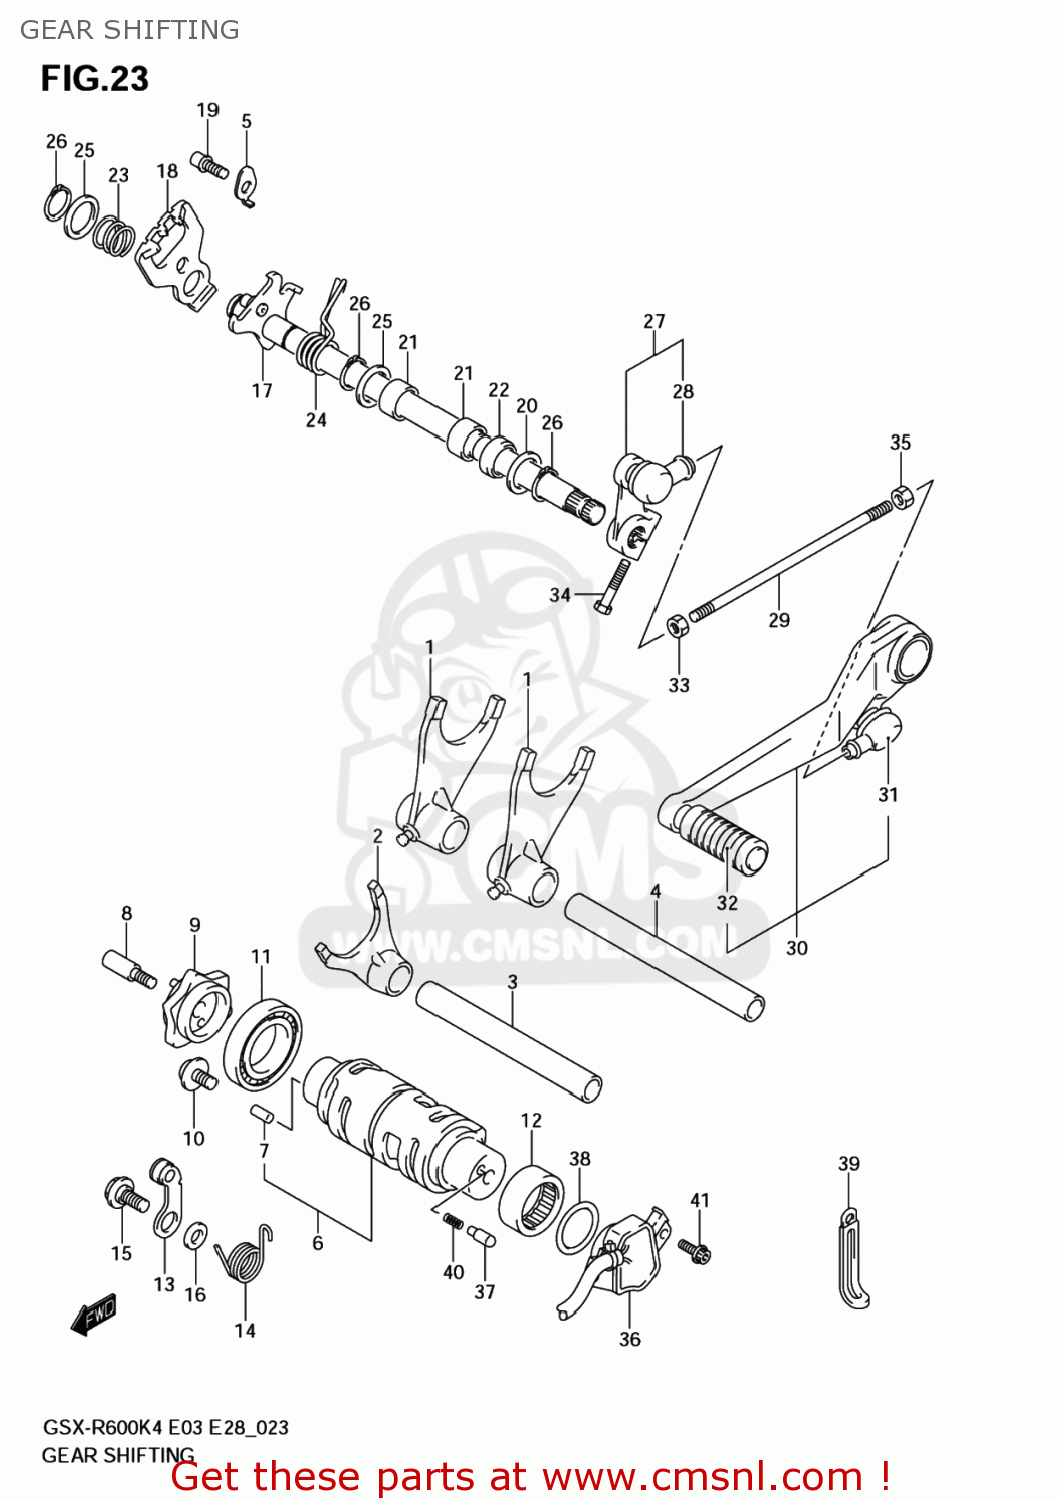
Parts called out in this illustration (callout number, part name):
1	FORK,GEAR SHIF
2	FORK,GEAR SHIF
3	SHAFT,GEAR SHIFT FORK
4	SHAFT,GEAR SHIFT FORK NO.1
5	RETAINER,GEAR SHIFT FORK SHAFT
6	CAM,GEAR SHIFT
7	PIN
8	BOLT,GEAR SHIF
9	PLATE,GEAR SHIFT CAM
10	SCREW(6X12)
11	BEARING(25X47X8)
12	BEARING(25X32X12)
13	STOPPER,SHIFT CAM
14	SPRING,SHIFT CAM STOPPER
15	BOLT(6X14.3)
16	WASHER
17	SHAFT,GEAR SHIFT
18	PLATE,GEAR SHIFT CAM DRIVE
19	STOPPER,GEAR SHIFT ARM
20	WASHER(14X29X0.8)
21	BEARING(14X20X12)
22	SEAL,OIL(14X22X6)
23	SPRING
24	SPRING
25	SHIM(14X22X1)
26	CIRCLIP
27	ARM,GEAR SHIFT LINK
28	COVER,DUST
29	ROD,GEAR SHIFT LINK
30	LEVER ASSY,GEAR SHIFT
31	COVER,DUST
32	RUBBER,GEAR SHIFT PEDAL
33	NUT
34	BOLT
35	NUT
36	BASE ASSY,GEAR SHIFT TERMINAL
37	PIN(5X15.5)
38	O RING(D:2.4,ID:25.7)
39	CLAMP(L:45)
40	SPRING
41	BOLT(5X16)
